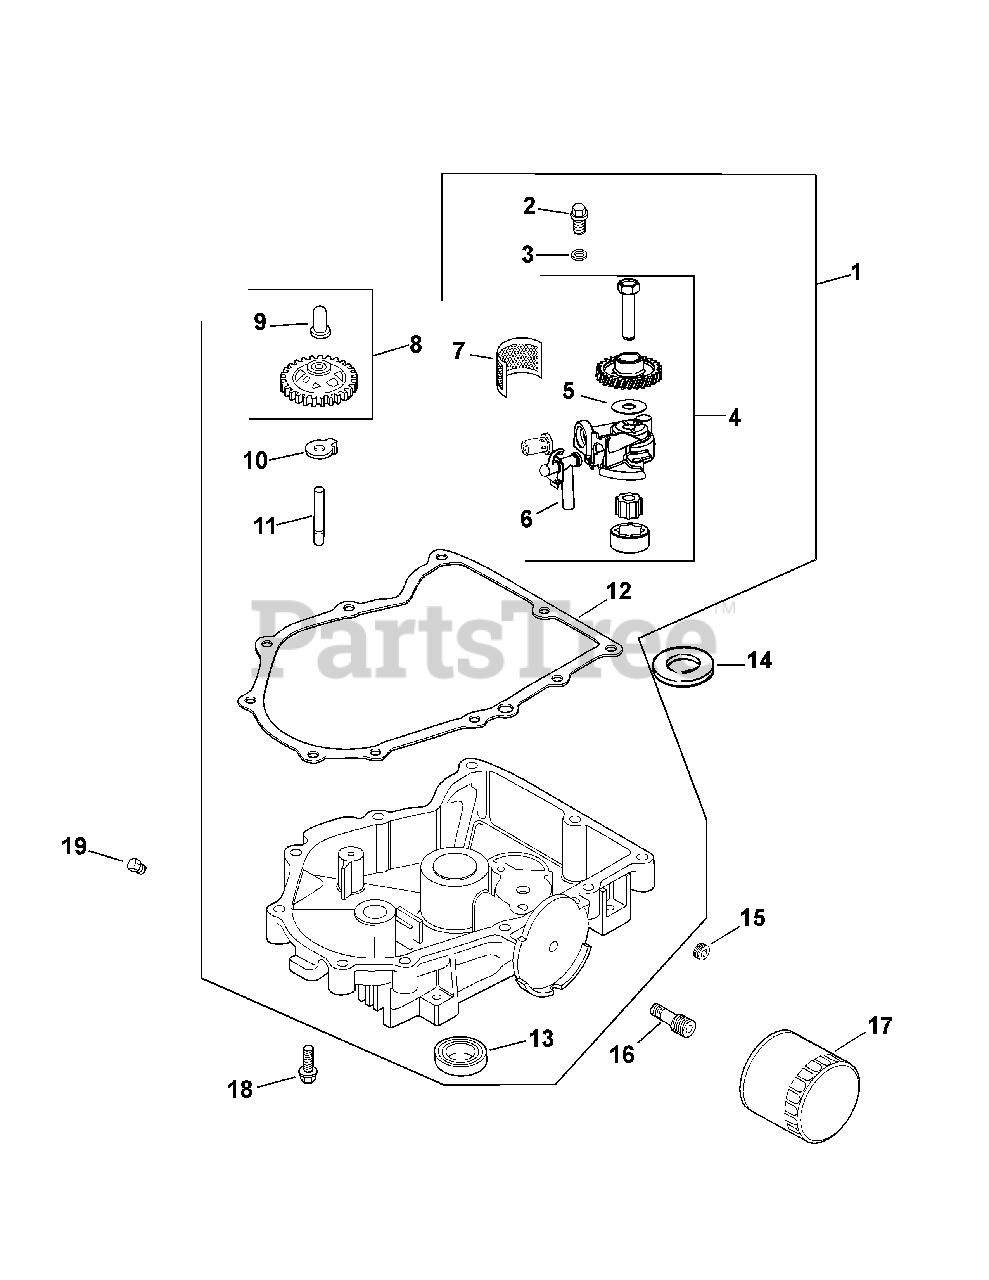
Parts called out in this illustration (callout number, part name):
1	Kit, Oil Pan Assembly (Inc. 2-13)
2	Screw, Flg Thd Frm M6X1.0X25
3	Washer, Flat 6MM
4	Kit, Oil Pump Assembly (Inc. 5, 6)
5	O-Ring, Oil Pick-Up
6	Tube, Oil Pick-Up
8	Kit, Governor Gear w/ Pin (Includes 9)
9	Pin, Governor Regulating
11	Shaft, Governor Gear
12	Kit, Oil Pan GSKT (Select-A-Seal)
15	Plug, Pipe CTSK 3/8"
16	Nipple, Oil Filter
18	Screw, Flg M8x1.25x45
19	Plug, Hd Pipe 3/8"
